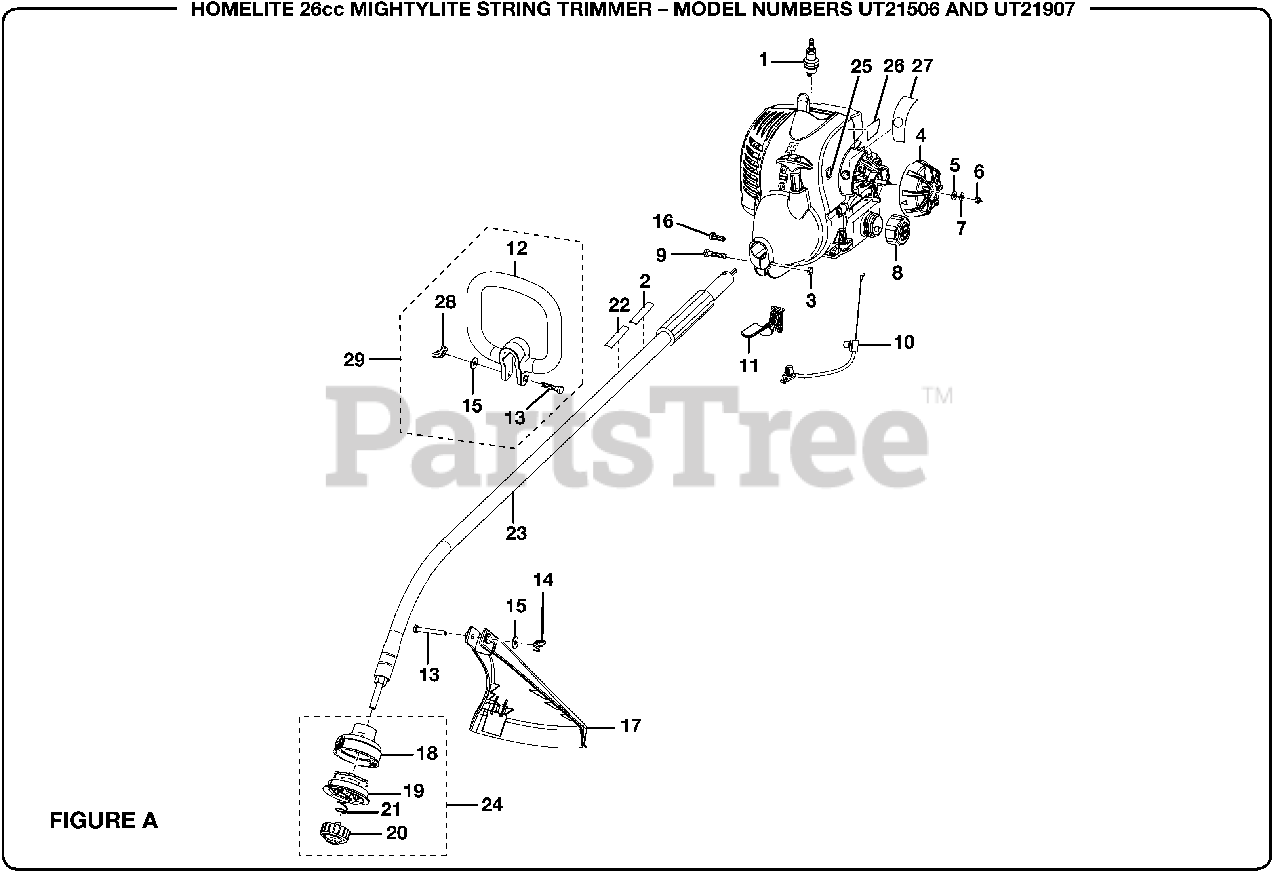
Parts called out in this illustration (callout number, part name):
1	Spark Plug
2	Starting Label
3	Hex Nut (M6)
4	Choke Dial Cover
5	Flat Washer
6	Hex Nut (M4)
7	Wavy Washer
9	Bolt (M6 x 20 mm)
10	Throttle Cable
11	Throttle Trigger
13	Bolt (1/4-20 x 40 mm)
14	Wing Nut (1/4-20)
15	Flat Washer
16	Screw (8-16 x 5/16 in.)
17	Curved Shaft Grass Deflector
18	String Head Housing
19	Single Line Spool and String
20	Spool Retainer
21	Spring
22	Warning Label
23	Boom Assembly
24	String Head Assembly
25	Switch
26	Logo Label
27	Choke Label
28	Wing Nut (1/4-20)
29	Handle Assembly
